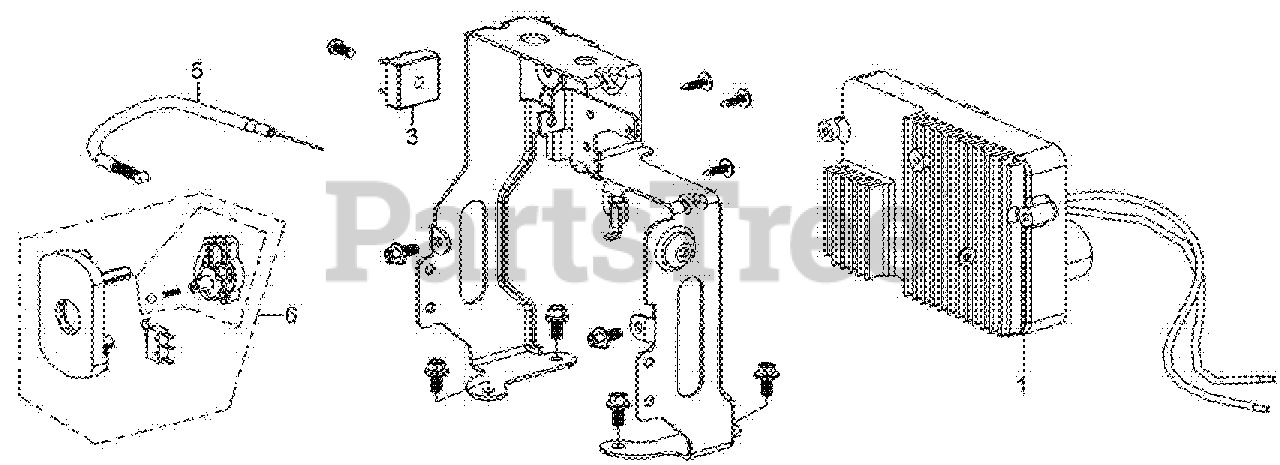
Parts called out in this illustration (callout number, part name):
1	INVERTER ASSY.
3	RECTIFIER BRIDGE
5	CHOKE CABLE
6	COMBINATION SWITCH
